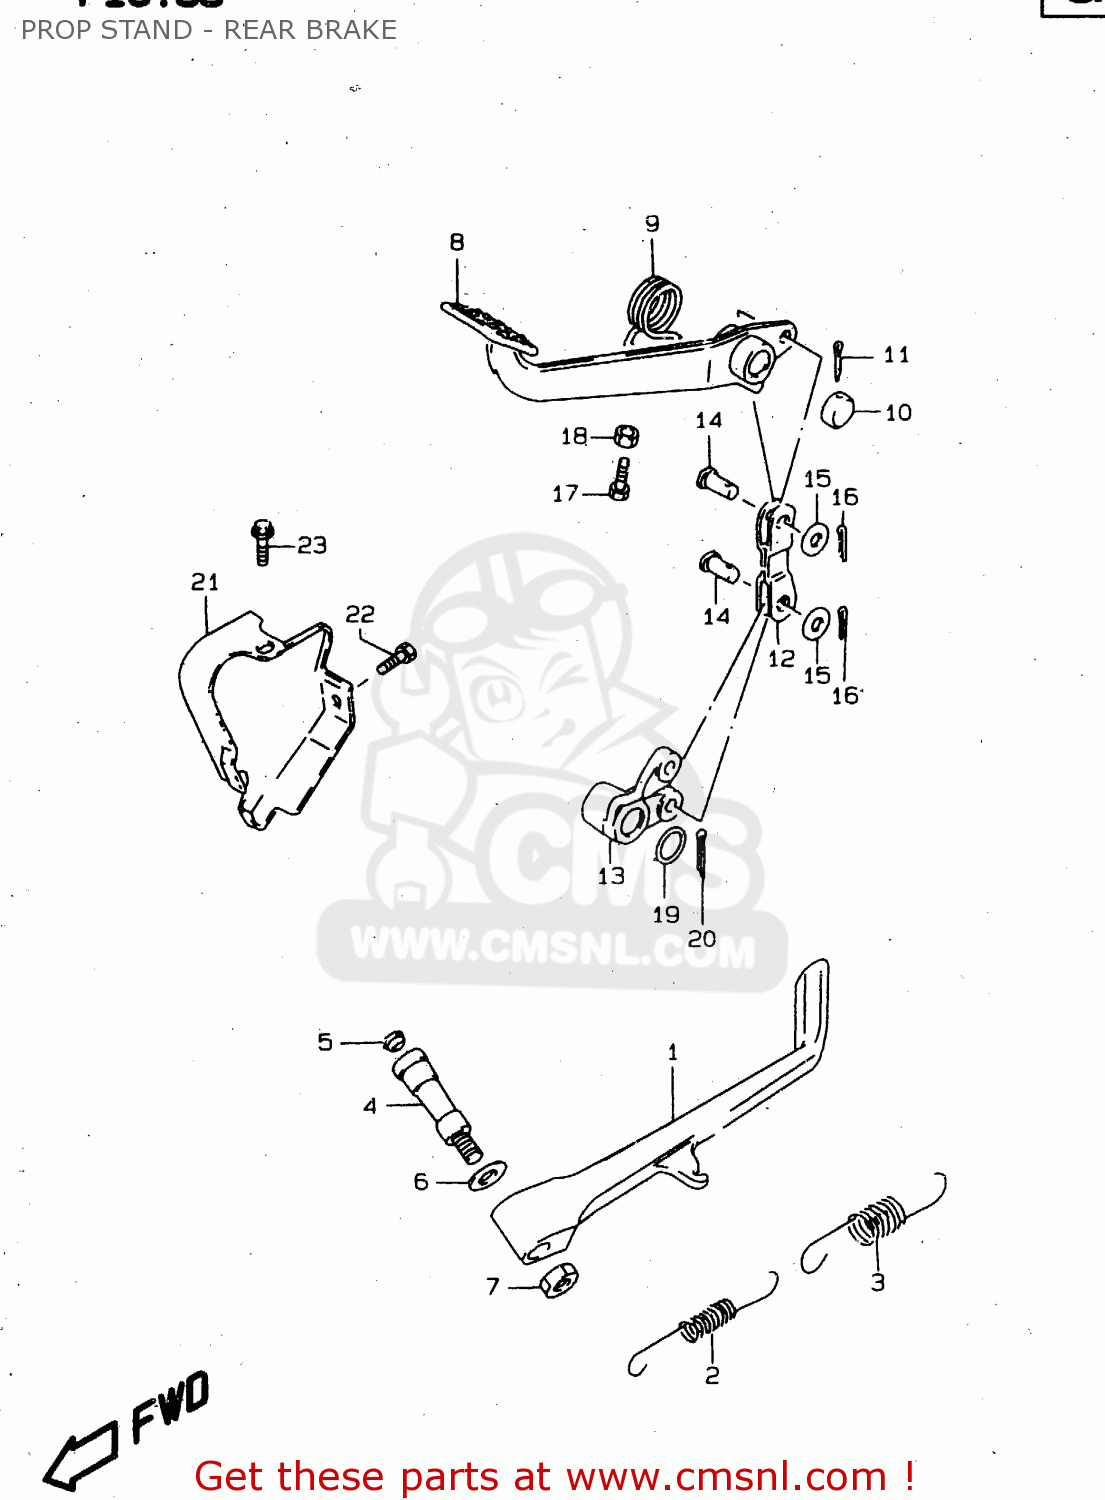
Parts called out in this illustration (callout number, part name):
1	STAND,PROP
2	SPRING
3	SPRING
4	BOLT,PROP STAND
5	CAP
6	SHIM(15X24X0.5)
7	NUT
8	PEDAL ASSY,BRAKE
9	SPRING
10	CAP,BRAKE PEDAL
11	COTTER PIN
12	LINK,BRAKE ROD NO.1
13	ARM,BRAKE PEDAL LINK
14	PIN
15	WASHER
16	PIN
17	BOLT
18	NUT
19	WASHER(16.5X22X1)
20	COTTER PIN
21	COVER,BRAKE
22	SCREW(6X10)
23	BOLT
